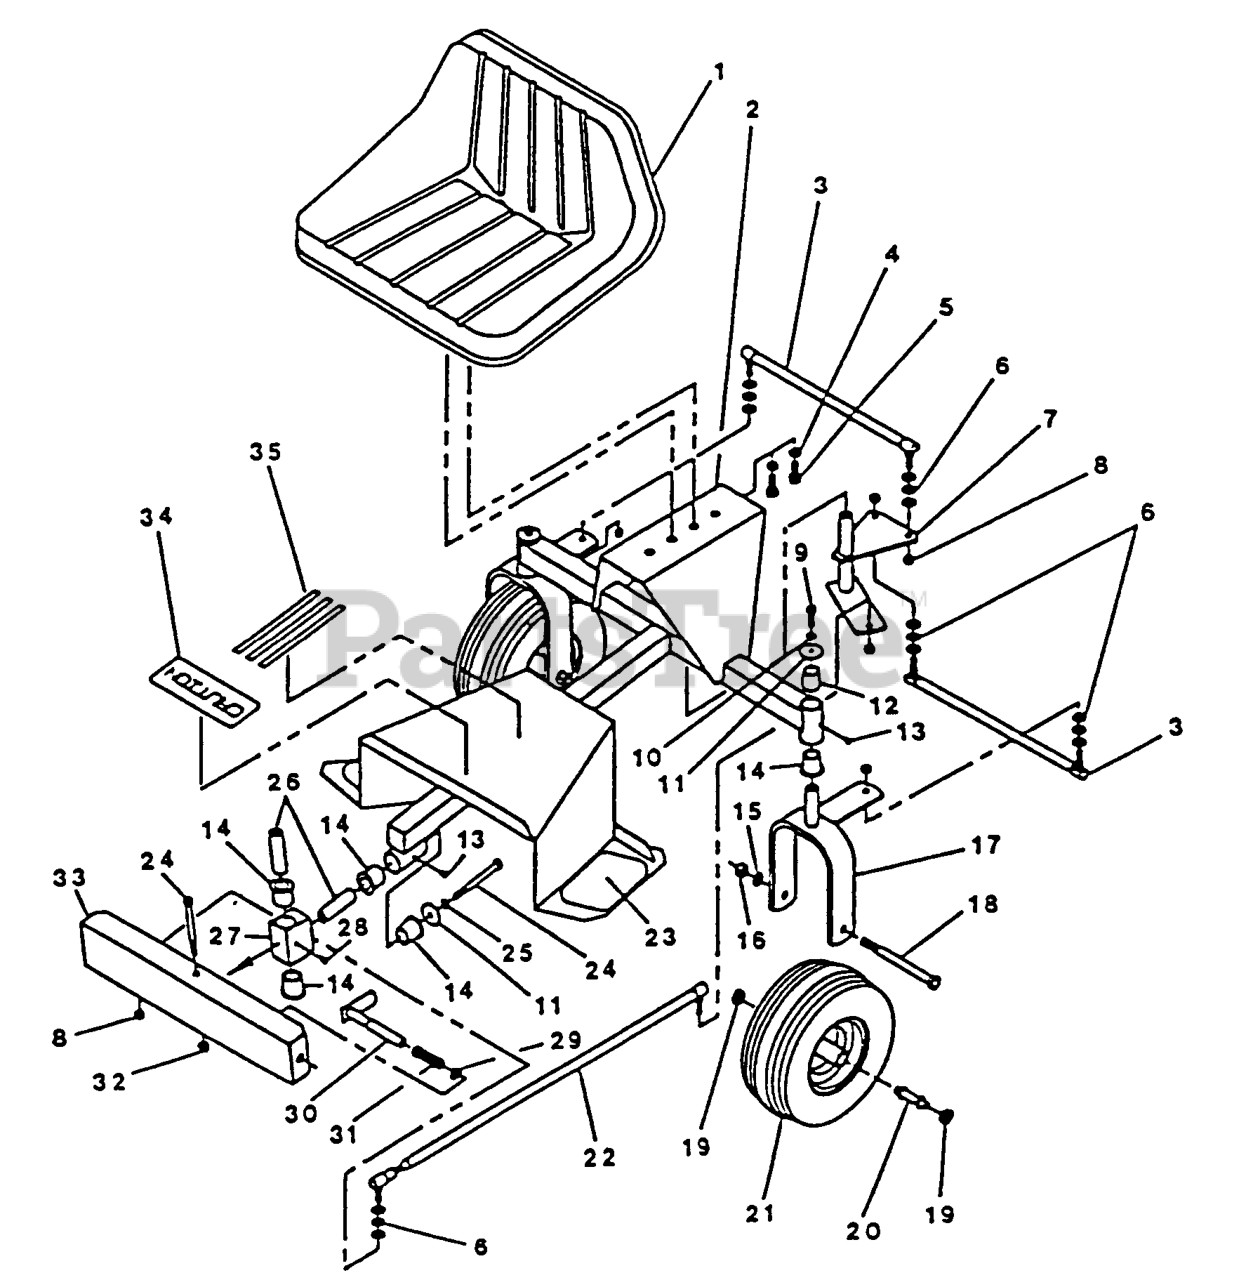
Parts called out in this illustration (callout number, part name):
3	ROD,STABILIZING
7	WLD,CRANK
10	WASHER-LOCK
12	BEARING,STRAIGHT
17	WLD,WHEEL SUPPORT
20	WLD,WHEEL SPACER
22	ROD-STEERING
26	PIN,CONNECTING
27	ASM,MOUNTING SWIVEL
31	SPRING,HITCH RELEASE
33	WLD,HITCH
